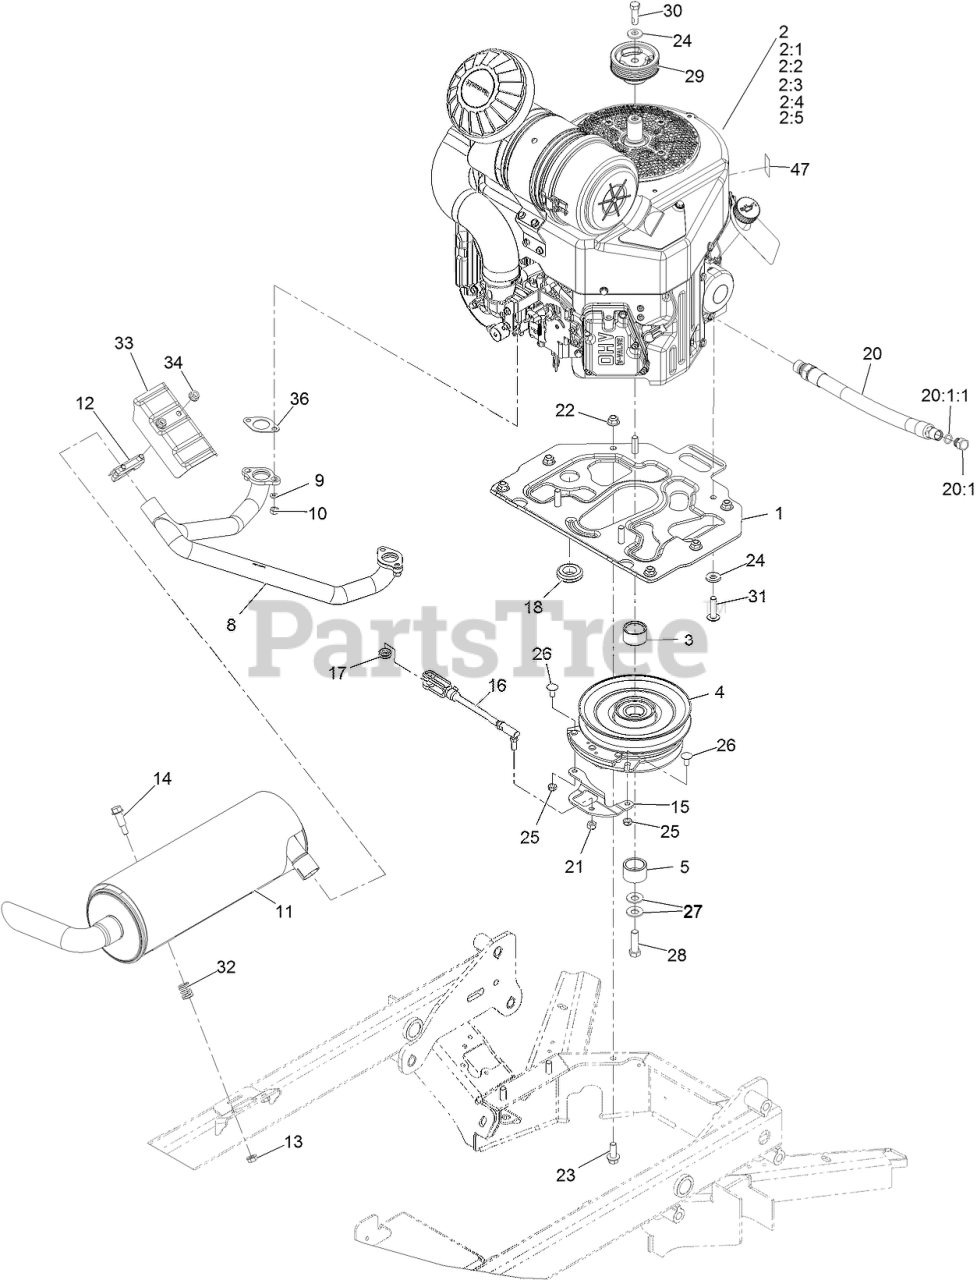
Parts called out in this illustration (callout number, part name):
1	Plate, Engine
2:1	Kawasaki 49065-7007 Engine Oil Filter
2:2	Kawasaki 49019-0031 Fuel Filter
2:4	Kawasaki 11013-7045 Pre-Filter
2:5	Kawasaki 11013-7044 Air Filter
3	Spacer, Clutch
4	CLUTCH
5	Spacer, Clutch
8	Header, Kawaswaki
9	WASHER-LOCK
11	Muffler, 5"
12	CLAMP-MUFFLER
14	Bolt-Shoulder
15	Strap, Clutch
16	ASM, CLUTCH ANCHOR
17	GROMMET
18	GROMMET
20	ENGINE OIL DRAIN HOSE ASM
20:1	PLUG-HH
20:1:1	O-RING
21	NUT-LOCK
22	NUT-HF, NI
23	SCREW-HHF 3/8-16 X 1
24	WASHER-BELLEVILLE
25	NUT-LOCK, NI
26	SCREW-CARR
27	WASHER-SPRING
28	SCREW-HH 7/16-20 X 1 1/2 W/LOCTITE
29	PULLEY, CRANK
30	Screw-HH, Patch
31	SCREW-BHTF
36	GASKET-EXHAUST
47	Decal-10W-50 Oil
